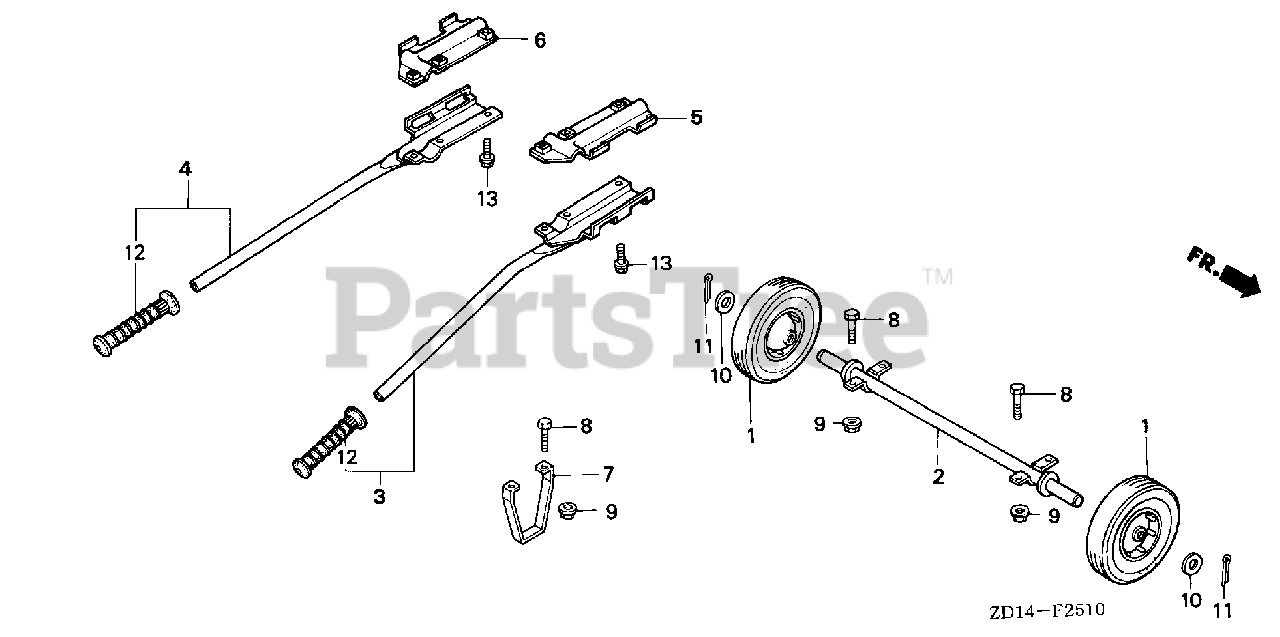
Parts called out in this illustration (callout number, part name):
1	WHEEL (10"X2.75")
2	SHAFT, WHEEL
3	HANDLE, R. (LOWER)
4	HANDLE, L. (LOWER)
5	BRACKET, R. HANDLE (UPPER)
6	BRACKET, L. HANDLE (UPPER)
8	BOLT, HEX. (8X16)
9	NUT, FLANGE (8MM)
10	WASHER, PLAIN (20MM)
11	PIN, SPLIT (4.0X28)
11	PIN, SPLIT (4.0X30)
12	GRIP D, R. HANDLE
13	BOLT, FLANGE (8X16)
